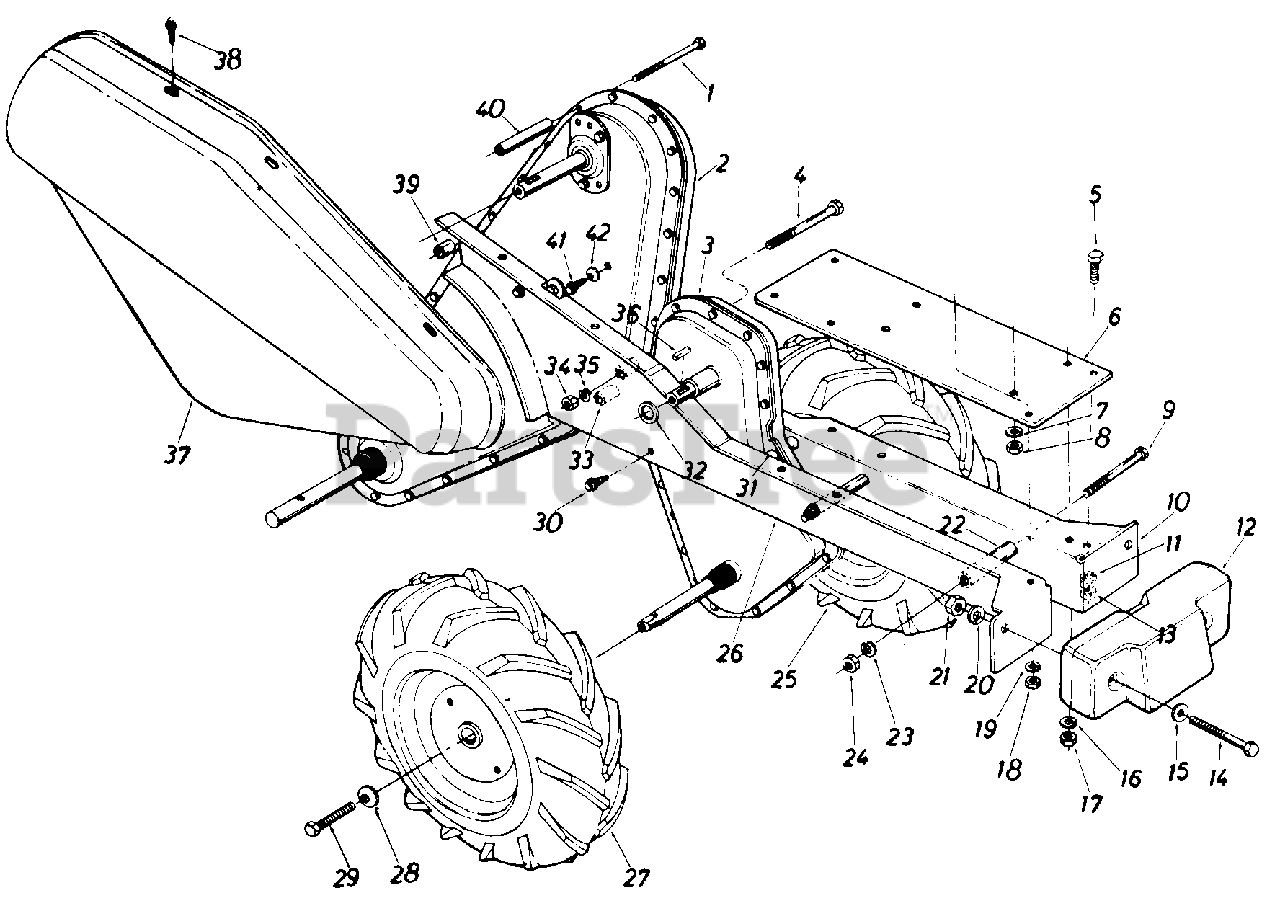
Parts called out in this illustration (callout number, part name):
1	Hex Bolt 5/16-18 x 3.00" Lg.
2	Chain Case Ass'y. Comp.-Tines
3	Chain Case Ass'y. Comp.-Wheels
4	Hex Bolt 5/16-18 x 3.00" Lg.
5	Hex Bolt 5/16-18 x .75" Lg.
8	Hex Nut 5/16-18 Thd.
9	Hex Bolt 3/8-24 x 3.00" Lg.
12	Weight 35#
13	Hex Nut 5/16-18 Thd.
14	Hex Bolt 1/2-13 x 4.00" Lg.
15	Fl-Wash. .510" I.D. x 1.0" O.D.
16	L-Wash. 5/16" I.D.
17	Hex Nut 5/16-18 Thd.
18	Hex Nut 5/16-18 Thd.
19	L-Wash. 5/16" I.D.
20	L-Wash. 1/2" I.D.
21	Hex Nut 1/2-13 Thd.*
22	Spacer .38" I.D. x .62" O.D. x 2.18" Lg.
23	L-Wash. 3/8" I.D.
24	Hex Nut 3/8-24 Thd.
25	Wheel Ass'y. Comp. 12.5 x 3.5-L.H.
28	Belleville Wash. .345" I.D. x.88" O.D.
29	Hex Bolt 5/16-24 x .62" Lg.
30	Hex Wash. Hd. SF-Tap Scr. 5/16-24 x 50" Lg.
31	Spacer .326" I.D. x .47" O.D. x .96" Lg.
32	Fl-Wash. .635" I.D. x 1.00" O.D.
33	Spacer .326" I.D. x .47" O.D. x .96" Lg.
34	Hex Nut 5/16-18 Thd.*
35	L-Wash. 5/16" I.D.
36	Sq. Key 3/16 x .75" Lg.
37	Belt Cover
38	Hex Wash. Hd. SF-Tap Scr. 1/4-20 x .50" Lg.
39	Spacer .326" I.D. x .47" O.D. x .96" Lg.
40	Spacer .375" I.D. x .500" O.D. x 2.00" Lg.
41	Hex Wash. Hd. SF-Tap Scr. 1/4-20 x .50" Lg.
42	Bell-Wash. .265" I.D. x .75"
